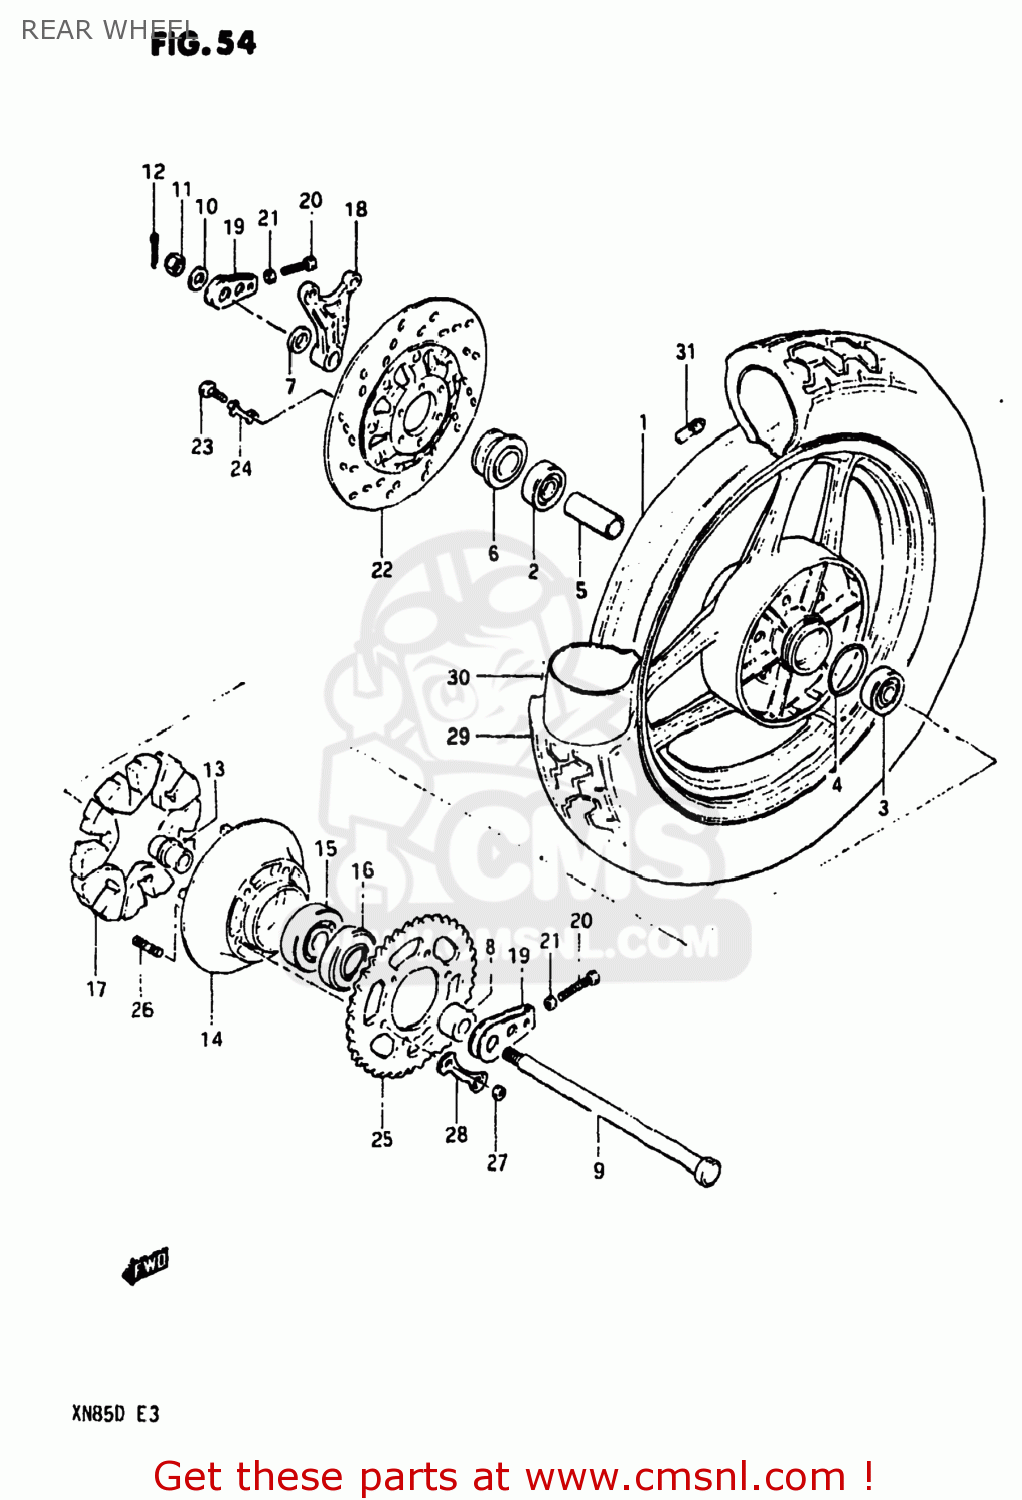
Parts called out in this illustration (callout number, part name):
1	WHEEL,REAR
2	BEARING WHEEL REAR(20X47X14)
3	BEARING, LH
4	O RING(D:2.4,ID:57.6)
5	SPACER
6	SPACER,REAR AXLE
7	SPACER
8	SPACER,REAR AXLE,LEFT
9	AXLE,REAR
10	WASHER(19X34X4)
11	NUT 18MM
12	PIN,COTTER
13	RETAINER,REAR SPROCKET
14	DRUM,REAR SPROCKET MOUNT
15	BALL BEARING 32X75X20
16	OIL SEAL
17	CUSHION,REAR DRUM
18	BRACKET,RR,CALIPER
19	ADJUSTER,CHAIN
20	BOLT 8X50
21	NUT
22	DISC,RR BRAKE
23	BOLT
24	WASHER
25	SPROCKET,REAR
26	BOLT(10X35.5)
27	NUT
28	WASHER
29	TIRE
30	TUBE ASSEMBLY,WHEEL,INNER
31	BALANCER,WHEEL
